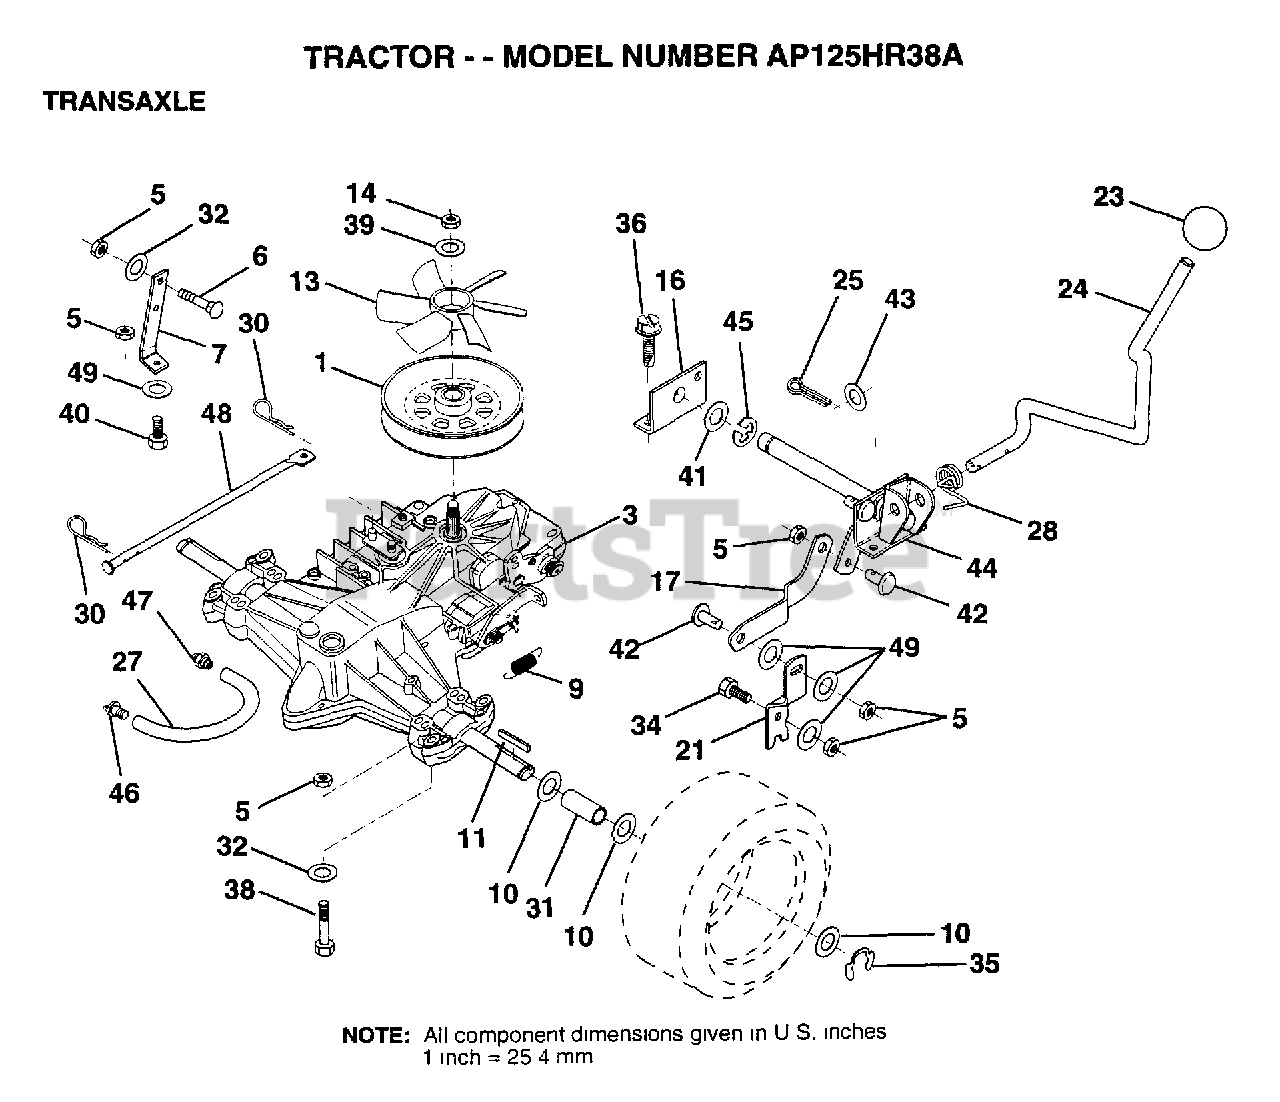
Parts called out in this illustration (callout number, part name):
1	PULLEY.V-GROOVE
3	TRANSAXLE HYD 0319-0500
5	NUT
6	BOLT
7	STRAP.TORQUE.HYD
10	WASHER
11	SQUARE KEY
13	FAN.HYDRO.6FANS
14	NUT STD
16	SUPPORT.HDLE.SHFT
17	LINK.SHIFT.HYD.LR
18	ACTUATOR.BYPASS
21	LEVER.SHIFT.TRANS
23	KNOB DLX BLK/BLK
24	ROD.SHIFTER.HYD.
25	PIN COTTER 1/8
27	"LINE FUEL HYD 4"""
28	SPRING.TORSION.LR
29	WASHER
30	RETAINER M
31	SPACER SPLIT
32	WASHER
35	E-RING LT
36	SCREW
38	BOLT
40	BOLT.HEX.5/16-1.5
41	WASHER
42	PIN.PIVOT.SHIFT.
43	WASHER
44	SHAFT.ASM.PIVOT
49	WASHER M
